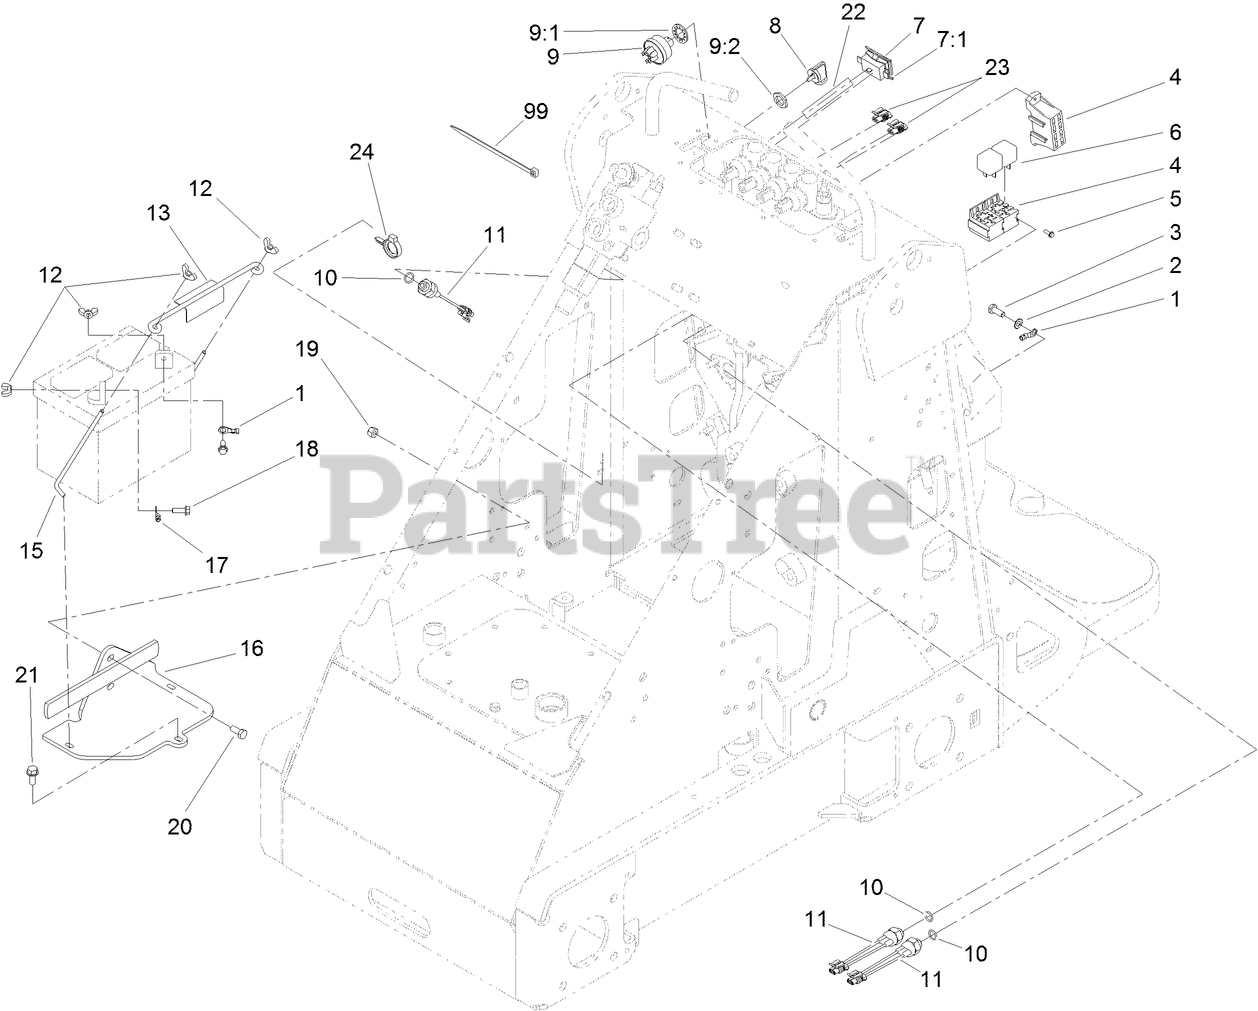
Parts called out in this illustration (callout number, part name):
1	WIRE ASM
2	WASHER-LOCK
3	SCREW-HH
4	HARNESS-WIRE
5	SCREW-HWHTF
6	RELAY
7	HOURMETER-INDUCTIVE
7:1	CLIP-MOUNTING
8	KEY-IGNITION
9:1	WASHER-LOCK
10	O-RING
11	SWITCH-BALL
12	NUT-WING
13	HOLDDOWN-BATTERY
15	RETAINER-BATTERY
16	BATTERY MOUNT ASM
17	CABLE-POSITIVE
18	SCREW-HHF
19	NUT-LOCK, NI
20	SCREW-HH
21	SCREW-HWHTF
22	WIRE-HOURMETER
23	CONNECTOR-FEMALE
24	CLAMP-HOSE
99	TIE-CABLE
